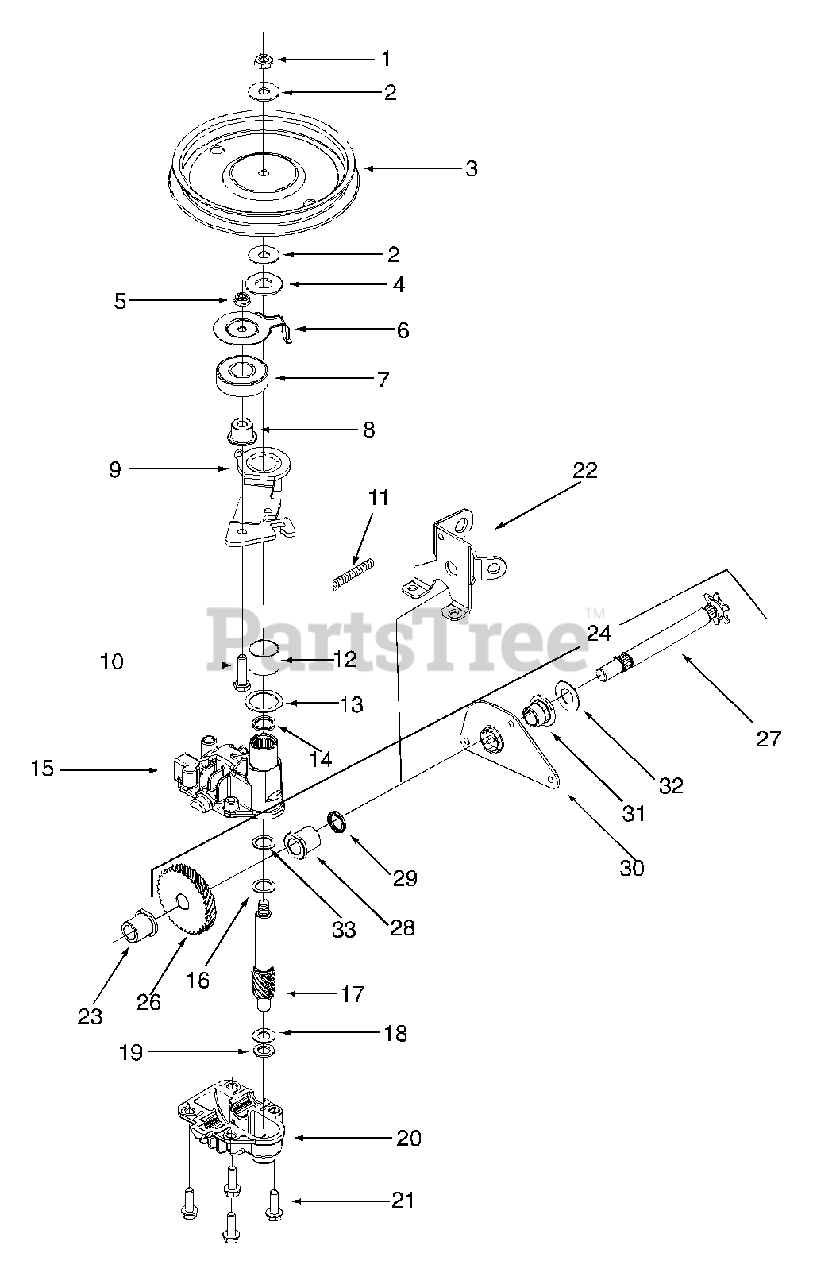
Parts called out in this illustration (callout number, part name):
1	Hx. Jam Nut 5/16-24
2	Bell Wash.325 x.930 x.045
3	Pulley
4	Fl. Wash.510 x 1.120 x.060
5	Hx. Jam Nut 1/4-28
6	Belt Keeper
7	Bearing
8	Flange Spacer
9	Idler Bracket Ass'y.
10	Hx. Cap Scr. 1/4-28 x 1.00 Gr. 5
11	Torsion Spring
12	Bearing Sleeve
13	Fl. Wash.885 x 1.145 x.030
14	Oil Seal
15	Upper Housing Ass'y.
16	Fl. Wash.504 x.700 x.030
17	Pinion Shaft 10 T.
18	Thr. Wash. 3/8 x.70 x.030
19	Thr. Wash.388 x.625 x.062
20	Lower Housing Ass'y.
21	Hx. Scr. 1/2-20 x.75
24	Shaft Ass'y.
26	Gear 34 T.
27	Output Shaft 6 T.
28	Flange Bearing
29	Oil Seal
30	Pivot Bracket
31	Flange Bearing
32	Fl. Wash.508 I.D. x 1.00 O.D. x.020
33	Thrust Bearing
